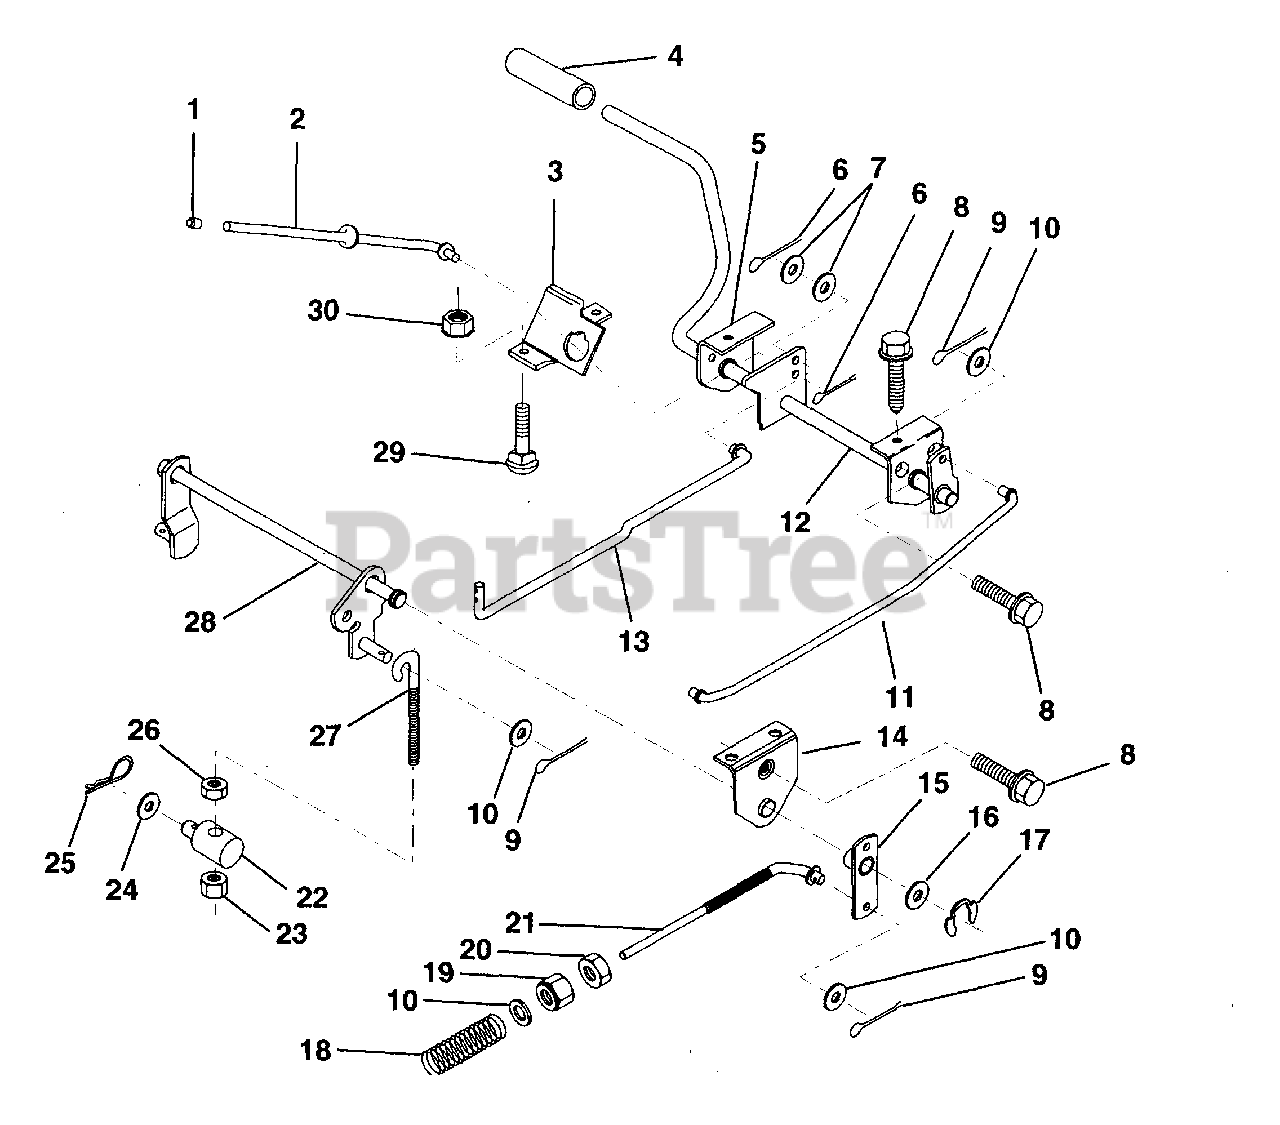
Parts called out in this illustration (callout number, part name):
1	Cap, Plunger
2	Rod, Parking Brake
3	Bracket, Parking Brake
4	Cover, Pedal
5	Bracket, Clutch/Brake Pedal, L.H.
6	Pin, Cotter 3/32 x 3/4
7	Washer 13/32 x 5/8 x 16 Gauge
8	Screw, Hex Head, Thd., Roll. 5/16-18 x 1/2
9	Pin, Cotter 1/8 x 3/4
10	Washer 13/32 x 13/16 x 16 Ga.
11	Rod, Brake Front
12	Assembly, Clutch/Brake Pedal
13	Rod, Clutch
14	Bracket, Lift, Shaft
15	Assembly, Brake, Pivot, Arm
16	Washer 25/32 x 1-1/8 x 16 Ga.
17	Ring, Klip
18	Spring, Brake Rod
19	Locknut, Hex, with Washer Insert 3/8-16 UNC
20	Nut, Hex, Jam 3/8-16 UNC
21	Rod, Rear, Brake
22	Trunnion, Lift
23	Nut, Crownlock 3/8-16 UNC
24	Washer 13/32 x 1-1/4 x 12 Ga.
25	Spring, Retainer
26	Nut, Centerlock 3/8-16 UNC
27	Link, Threaded
28	Assembly, Rear Mower Lift
29	Bolt, Carriage 5/16-18 UNC x 3/4
30	Nut, Hex, Keps 5/16-16 UNC
